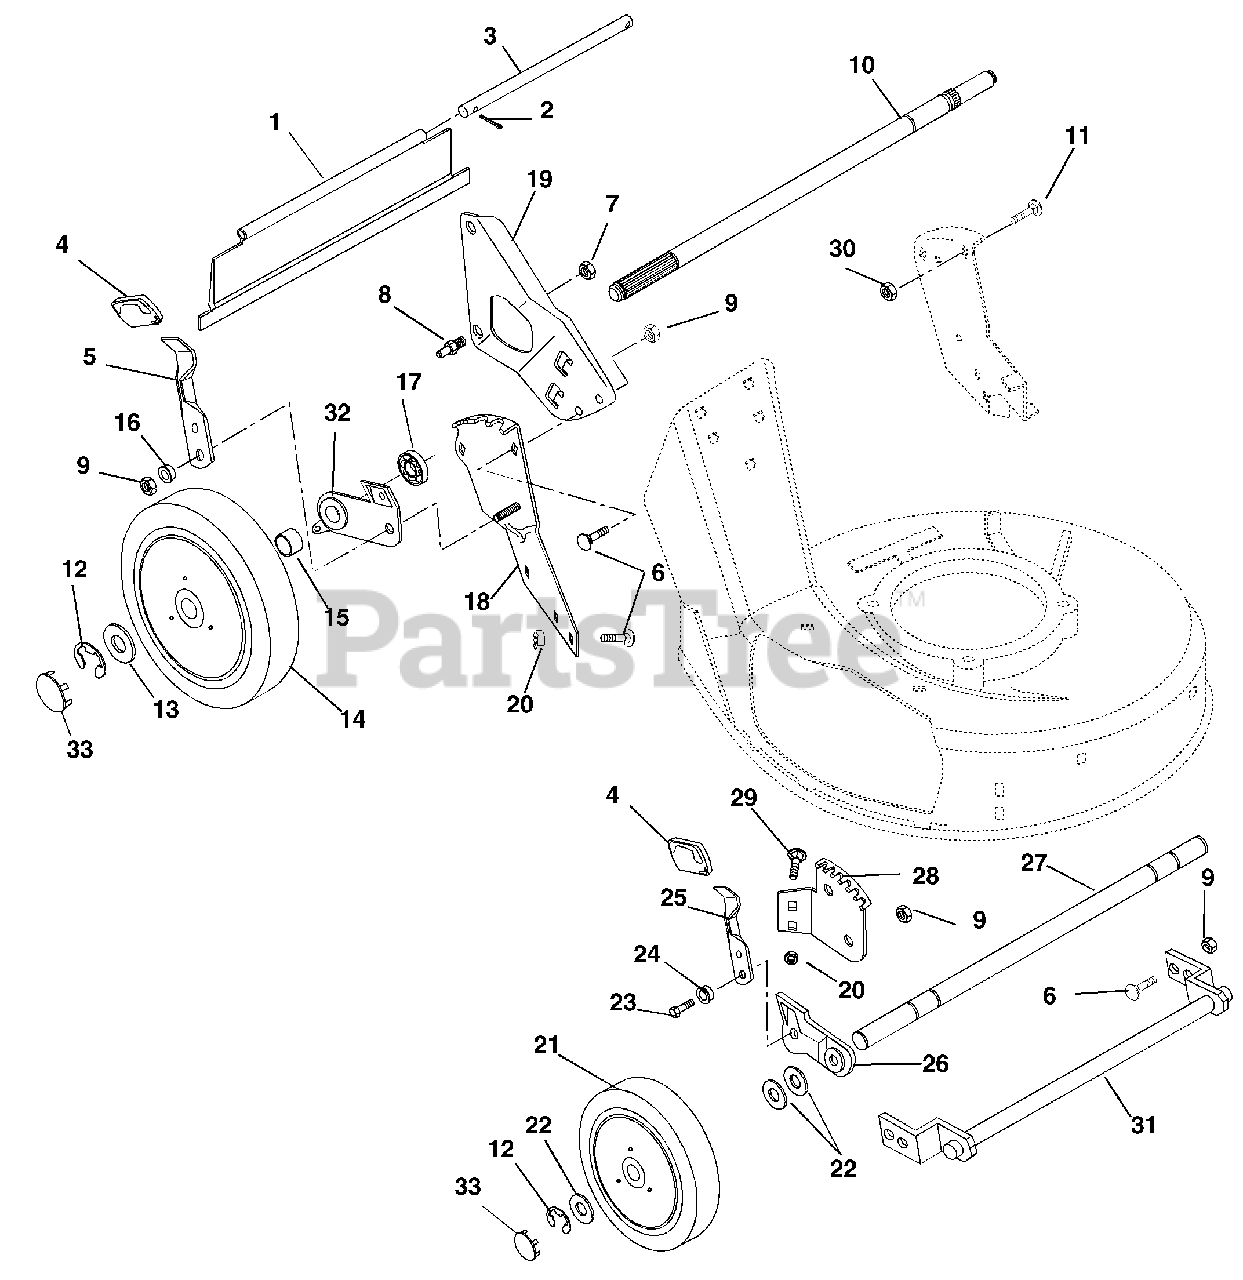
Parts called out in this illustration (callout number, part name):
1	Rear Protective Guard, Self Propelled
1	Rear Protective Guard, Push
2	Pin-Cotter .06 x .50
4	Knob
5	Height Adjustment Lever
6	Bolt-Round Head Square Short Neck .31-18 x .62
7	Nut-Locking-Center .38-16
8	Handlebar Stud
9	Nut-Locking-Center .31-18
10	Rear Axle
10	Rear Axle Push Mower
11	Bolt-Round Head Square Short Neck .31-18 x 1.00
12	Ring-Retaining-External .500 x .042
13	Washer-Flat-Steel .505 x .880 x .072
14	Wheel,Left Hand Rear
14	Wheel Right Hand Rear
14	Wheel, Push
15	Spacer Tube
15	Spacer Tube-Push Left Hand
15	Spacer Tube-Push Right Hand
16	Bushing-Flange .312 x .500 x .344 x .880
17	Bearing-Ball .625 x 1.383 x .50
18	Rear Quadrant-Left Hand
18	Rear Quadrant-Right Hand
19	Bracket-Handlebar Mounting-Right Hand
19	Bracket-Handlebar Mounting-Left Hand
20	Nut-Locking-Flanged .31-18
21	Wheel-Front
22	Washer-Flat-Steel .520 x .827 x .062
23	Bolt-Hex .31-18 x 1.00 Grade 5
24	Bushing-Flange .312 x .500 x .344 x .880
25	Lever, Front Height Adjustment
26	Left Hand Bracket Assembly
26	Right Hand Bracket Assembly
27	Front Axle
28	Front Quadrant, Left Hand
28	Front Quadrant, Right Hand
29	Bolt-Round Head Square Neck .31-18 x .50 Grade 5
30	Nut-Locking-Nylon .31-18
31	De-Thatcher Retainer Weldment
32	Rear Adjuster Bracket-Right Hand
32	Rear Adjuster Bracket-Left Hand
32	Rear Bracket and Bearing Assembly
